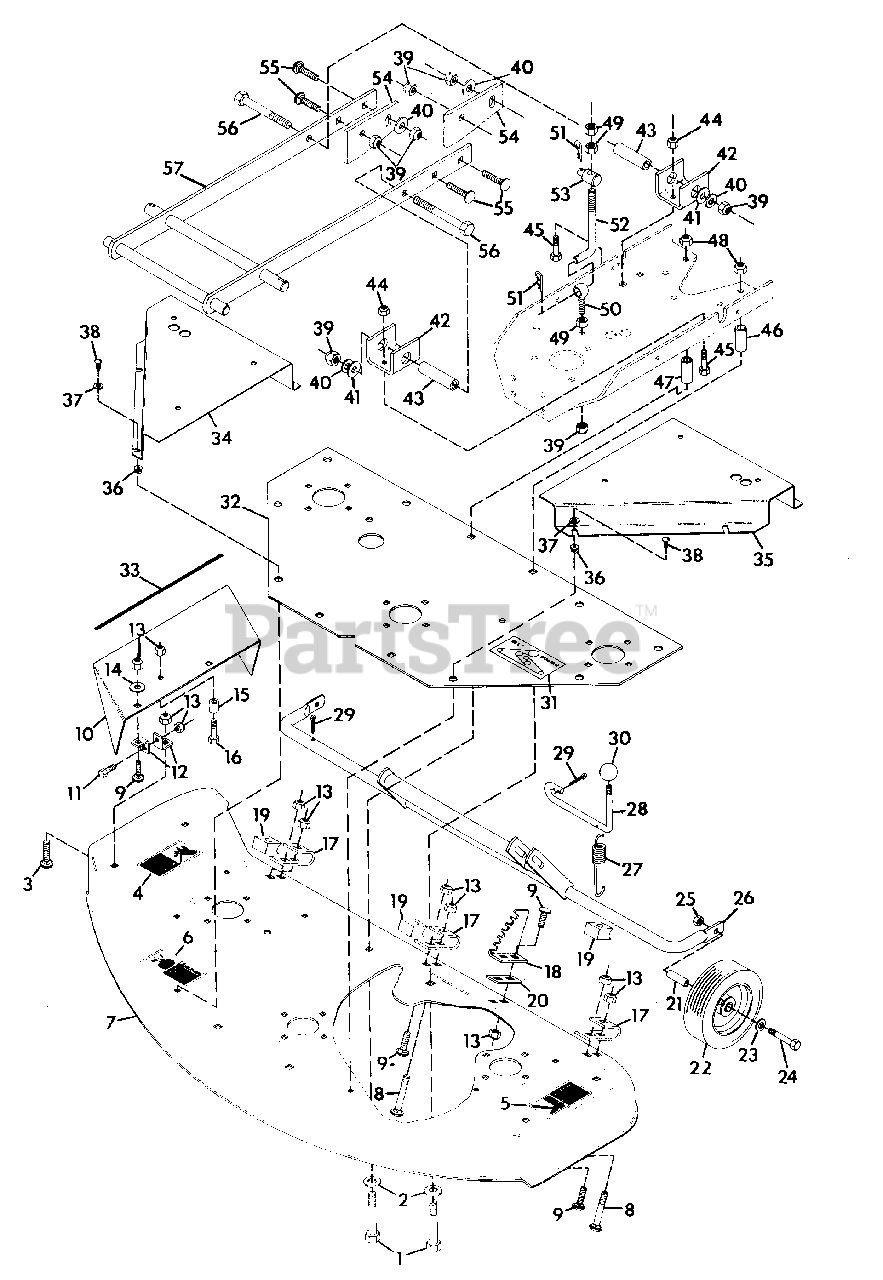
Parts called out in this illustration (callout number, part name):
1	BOLT, HEX 1/2-13X3.75
2	WASHER, FLAT .531X1.062X.095
3	BOLT, 3/8-16X.75 RD. HD. SQ. NK.
4	DECAL, DANGER HAND
5	DECAL, DANGER FOOT
6	DECAL, WARNING EYE
7	WELDMENT, 40 IN. DECK
8	BOLT, 3/8-16X2 RD. HD. SQ. NK.
9	BOLT, 3/8-16X1 RD. HD. SQ. NK.
10	CHUTE, 40" FLIP-UP
11	BOLT, HEX 3/8-16X.875
12	TAB, SPRING
13	NUT, LOCK 3/8-16
14	WASHER, FLAT .406X.812X.065
15	STOP, CHUTE
16	BOLT, HEX 3/8-16X1.50
17	BRACKET, AXLE SUPPORT
18	BRACKET, HEIGHT ADJUST
19	STOP, NYLON
20	SHIM, MOWER HT. ADJ. BKT.
21	BUSHING, .750X.375X1.785
22	WHEEL, GAUGE
23	WASHER, FLAT .438X1.375X.083
24	BOLT, HEX 3/8-16X2.5
25	NUT, JAM 3/8-16
26	AXLE, PIVOT WELDMENT
27	SPRING, 40 & 50 INCH MOWER
28	LEVER, HEIGHT ADJUST.
29	PIN, COTTER 1/8X1.25
30	KNOB, ADJ. CONTROL
31	DECAL, BELT INSTALLATION
32	PLATE, SUPPORT
33	STRIPE
34	COVER, PULLEY R.H. 40
35	COVER, PULLEY L.H. 40
36	GROMMET, PLASTIC
37	WASHER, FLAT .281X.625X.065
38	SCREW, TAPPING 1/4-20X.62
39	NUT, LOCK 1/2-13
40	WASHER, FLAT .531X1.250X.100
41	WASHER, FLAT .813X1.37X.100
42	SUPPORT, MOWER PIVOT
43	BUSHING, MOWER PIVOT .510X.750
44	NUT, LOCK 5/16-18
45	BOLT, HEX 5/16-18X.875
46	SPACER, .510X.840X2.43
47	SPACER
48	NUT, LOCK 1/2-13
49	NUT, JAM 1/2-13
50	BOLT, EYE
51	COTTER, HAIR PIN
52	ROD, LIFT
53	PIVOT, MOWER LIFT
54	PLATE, ADJUSTMENT
55	BOLT, CARRIAGE 1/2-13X1.25
56	BOLT, HEX 1/2-13X3.00
57	WELDMENT, PIVOT ARM
NS	DECAL, AMERICA
